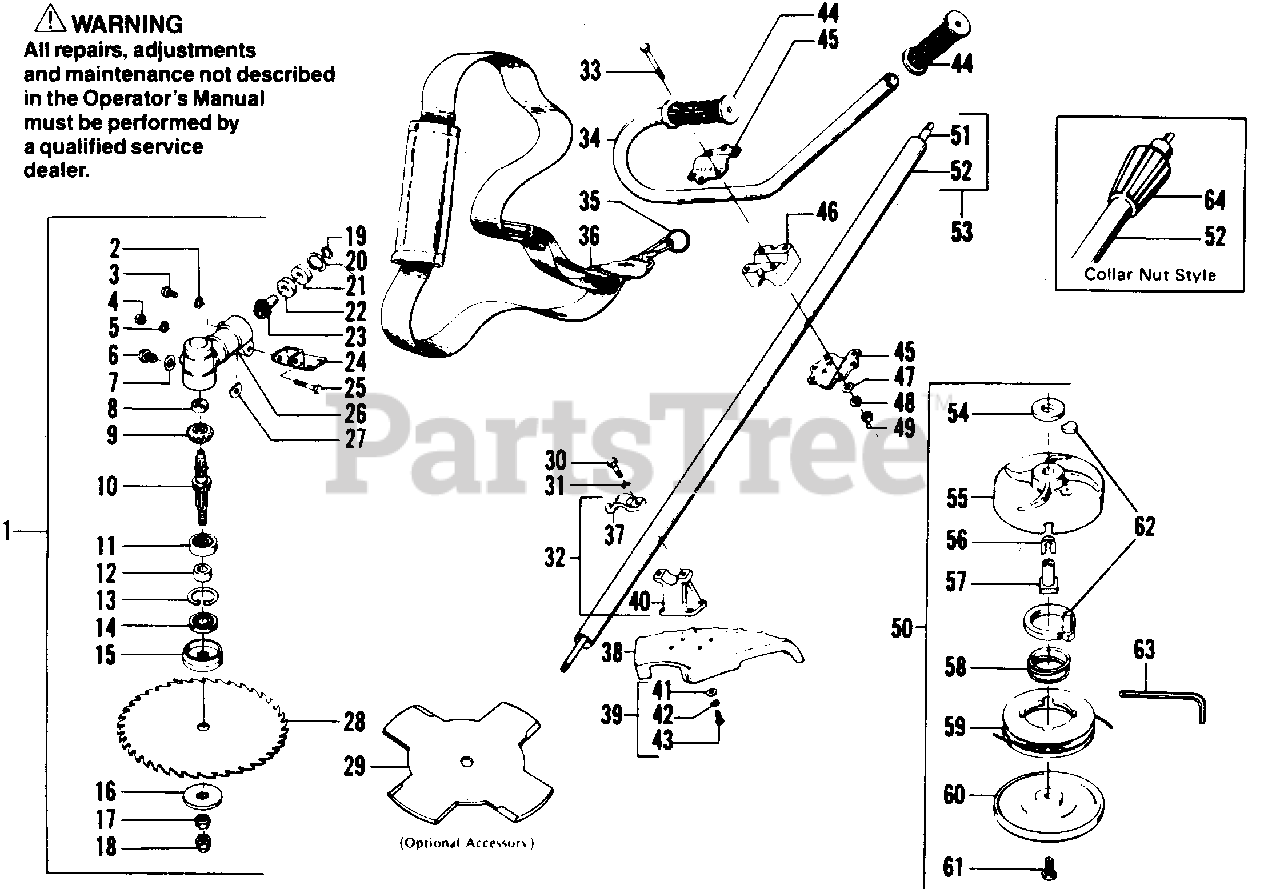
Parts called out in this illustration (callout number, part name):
1	Gear Box Ass'y w/fasteners (Inc. 2-27)
2	Lockwasher - Housing Bolt
3	Bolt - 6 x 12mm
4	Nut - 6mm - Housing (Gear Box)
5	Lockwasher - 6mm - Housing (Gear Box)
6	Oil Plug
8	Bearing - Gear Box
9	Gear - Bevel
10	Shaft - Splined Drive
11	Ball Bearing
12	Collar - Shaft
13	Snap Ring
14	Oil Seal
15	Blade Adaptor - Upper
16	Blade Adaptor - Lower
19	Snap Ring - Gear Housing
20	Snap Ring - Gear Housing Bearing
21	Bearing - Sealed Pinion Gear
22	Bearing - Pinion Gear
23	Pinion Gear
24	Bracket-Shield to Gear Box, See Service Ref.1
25	Bolt 6 x 42mm - Housing (Gear Box)
26	Housing - Gear Box
27	Fiber - Filler Washer
28	10" Brush Blade
29	8" Weed Blade (Optional)
30	Bolt - 5 x 25mm
31	Washer - 5mm
32	Shield Mounting Bracket Ass'y (Inc. 37 & 40)
33	Bolt -#1/4 - 20 x 1 - 7/8" - Handlebar
34	Handlebar
35	Key-Ring - Shoulder Strap
36	Shoulder Harness Strap
37	Shield Mounting Bracket - Top
38	Shield w/fasteners
39	Shield Mounting Kit (Inc. 41,42,43 - 4 each)
40	Shield Mounting Bracket - Bottom
41	Washer - 4mm - Flat
42	Lockwasher - 4mm
43	Screw - 4mm x 16mm
44	Grip - Handlebar
45	Handlebar Clamp
46	Handlebar Block
47	Washer - Handlebar
48	Lockwasher - Handlebar
49	Nut - #1/4 - 20
50	Cutting Head Assembly (Inc. 54-63)
51	Drive Shaft
52	48" Drive Shaft Housing w/bearings
52	Collar Nut Style (Incl. #64)
52	Pinch Clamp Style
53	48" Drive Shaft Housing and Drive Shaft Ass'y (Inc. 51 & 52)
56	Line Saver
57	Drive Adaptor
59	Spool w/line
60	Cover - Cutting Head
61	Screw - #3/8 - 16 x 7/8" - Cover
62	Release Button Ass'y (Incl. Lock Ring)
63	Allen Wrench - Cutting Head
64	Collar Nut
